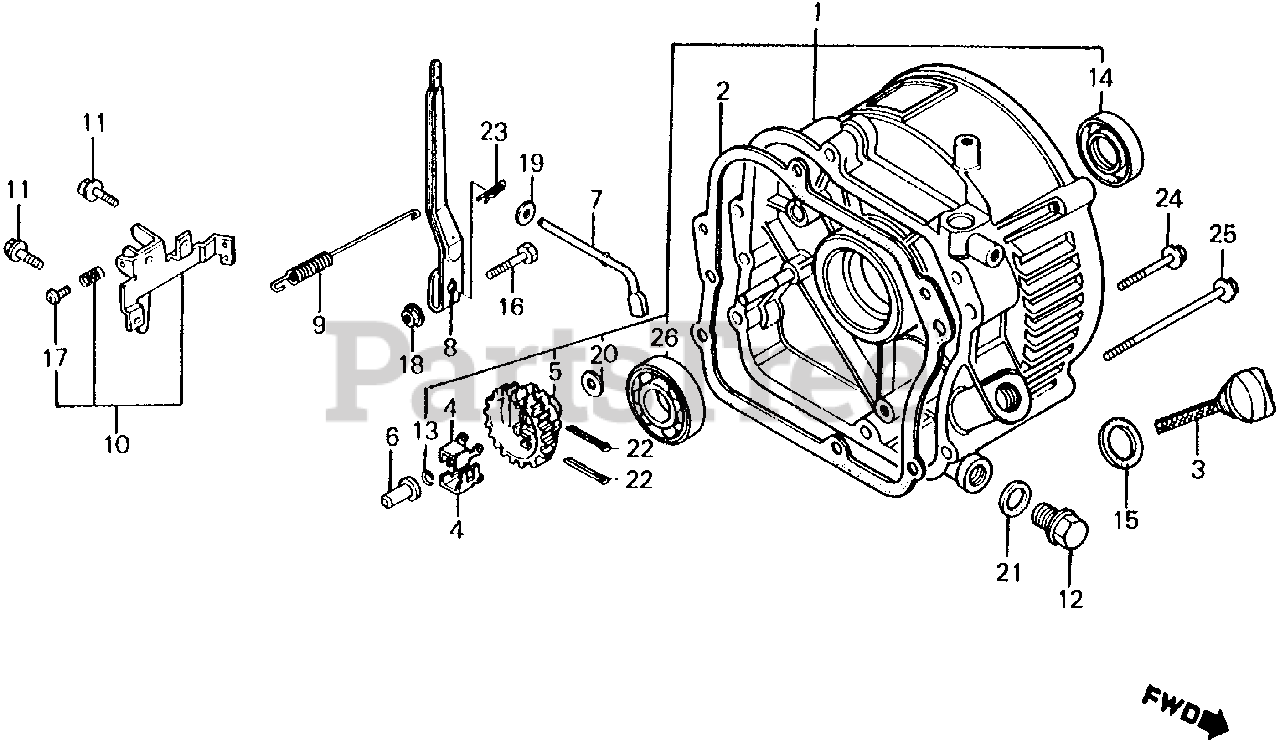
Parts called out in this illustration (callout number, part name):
1	COVER ASSY., CRANKCASE
2	GASKET, CASE COVER
3	CAP, OIL FILLER
4	WEIGHT, GOVERNOR
5	HOLDER, GOVERNOR WEIGHT
5	HOLDER, GOVERNOR WEIGHT (NOT AVAILABLE)
6	SLIDER, GOVERNOR
7	SHAFT, GOVERNOR ARM
8	ARM, GOVERNOR
9	SPRING, GOVERNOR (NOT AVAILABLE)
10	ADJUSTER ASSY., THROTTLE
11	BOLT, FLANGE (5X10)
12	BOLT, DRAIN PLUG
13	CLIP, GOVERNOR HOLDER
14	OIL SEAL (17X30X6) (NOK)
15	O-RING (16MM)
16	BOLT, HEX. (6X20)
17	SCREW, PAN (4X14)
18	NUT, FLANGE (6MM)
19	WASHER, PLAIN (5MM)
20	WASHER, PLAIN (6MM)
21	WASHER, DRAIN PLUG (12MM)
22	PIN, GOVERNOR WEIGHT
22	PIN, COTTER (2.5X28)
23	PIN, LOCK (8MM)
24	BOLT, FLANGE (6X28)
25	BOLT, FLANGE (6X80)
26	BEARING, RADIAL BALL (6203)
